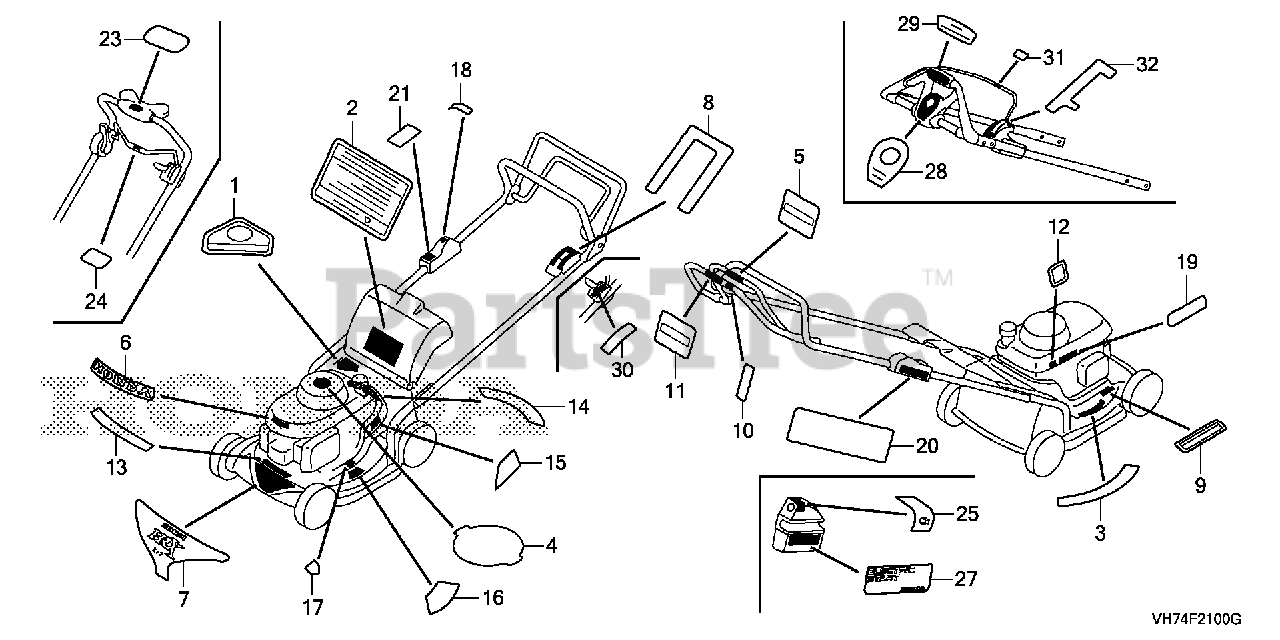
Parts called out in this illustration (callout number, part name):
1	CAUTION C, HOUSING
2	LABEL, WARNING (ENGLISH)
4	MARK, RECOIL COVER
5	MARK, CLUTCH INDICATION (ENGLISH)
7	MARK, HONDA
8	MARK, THROTTLE INDICATION (ENGLISH)
9	LABEL, HEAT WARNING
10	MARK, BLADE CONTROL
11	MARK, BLADE CONTROL (ENGLISH)
12	MARK, OIL CAUTION
13	MARK, SALES POINT (HRX)
14	MARK, CONTROL
15	MARK, CLIP DIRECTOR
19	MARK, OIL RECOMMENDED
